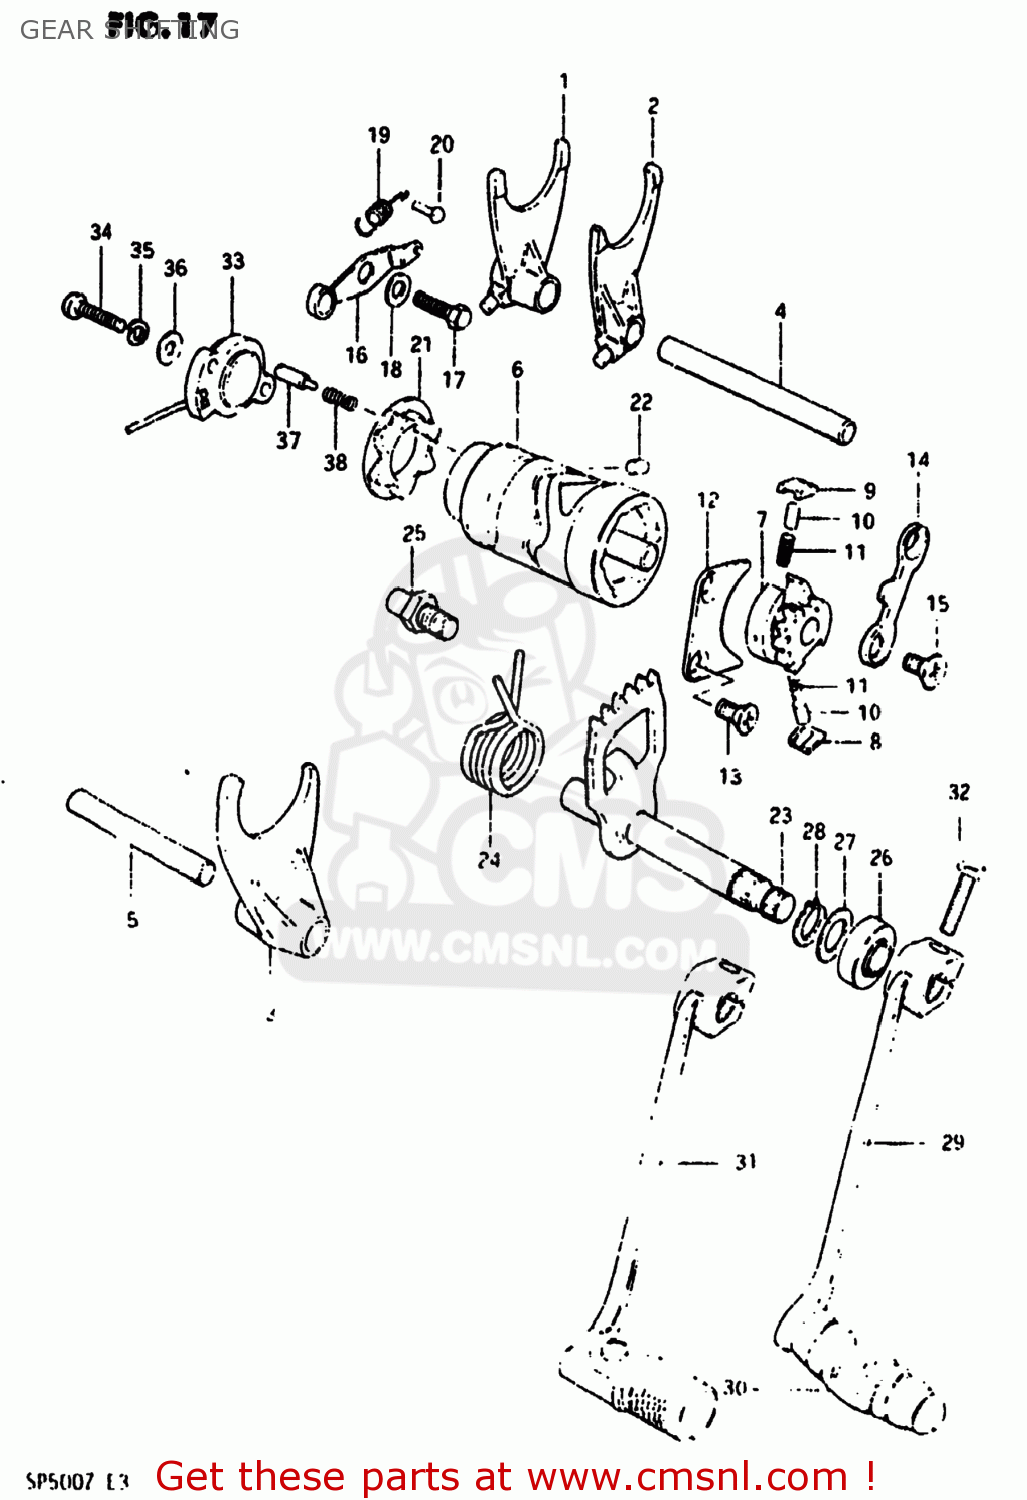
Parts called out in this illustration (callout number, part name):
1	FORK,GEAR SHIFT NO.1
2	FORK,GEAR SHIFT NO.2
3	FORK,GEAR SHIFT NO.3
4	SHAFT,GEAR SHIFT FORK
5	SHAFT,GEAR SHIFT FORK
6	CAM,GEAR SHIFT
7	SHIFTER,GEAR SHIFT CAM
8	PAWL,GEAR SHIFT NO.1
9	PAWL,GEAR SHIFT NO.2
10	PIN(5X8)
11	SPRING
12	LIFTER,GEAR SHIFT PAWL
13	SCREW
14	GUIDE,GEAR SHIFT CAM
15	SCREW
16	STOPPER,GEAR SHIFT CAM
17	BOLT
18	WASHER
19	SPRING
20	RIVET
21	PLATE,SHIFT CAM STOPPER
22	PIN 4X6
23	SHAFT,GEAR SHIFT
24	SPRING
25	STOPPER,GEAR SHIFT CAM
26	OIL SEAL
27	WASHER
28	CIRCLIP
29	LEVER ASSEMBLY,GEAR SHIFTING
30	RUBBER,GEAR SHIFT PEDAL
31	LEVER ASSEMBLY,GEAR SHIFTING
32	BOLT
33	BASE ASSEMBLY,NEUTRAL SWITCH TERMINAL
34	SCREW
35	LOCK WASHER
36	WASHER
37	PIN(5X15.5)
38	SPRING
